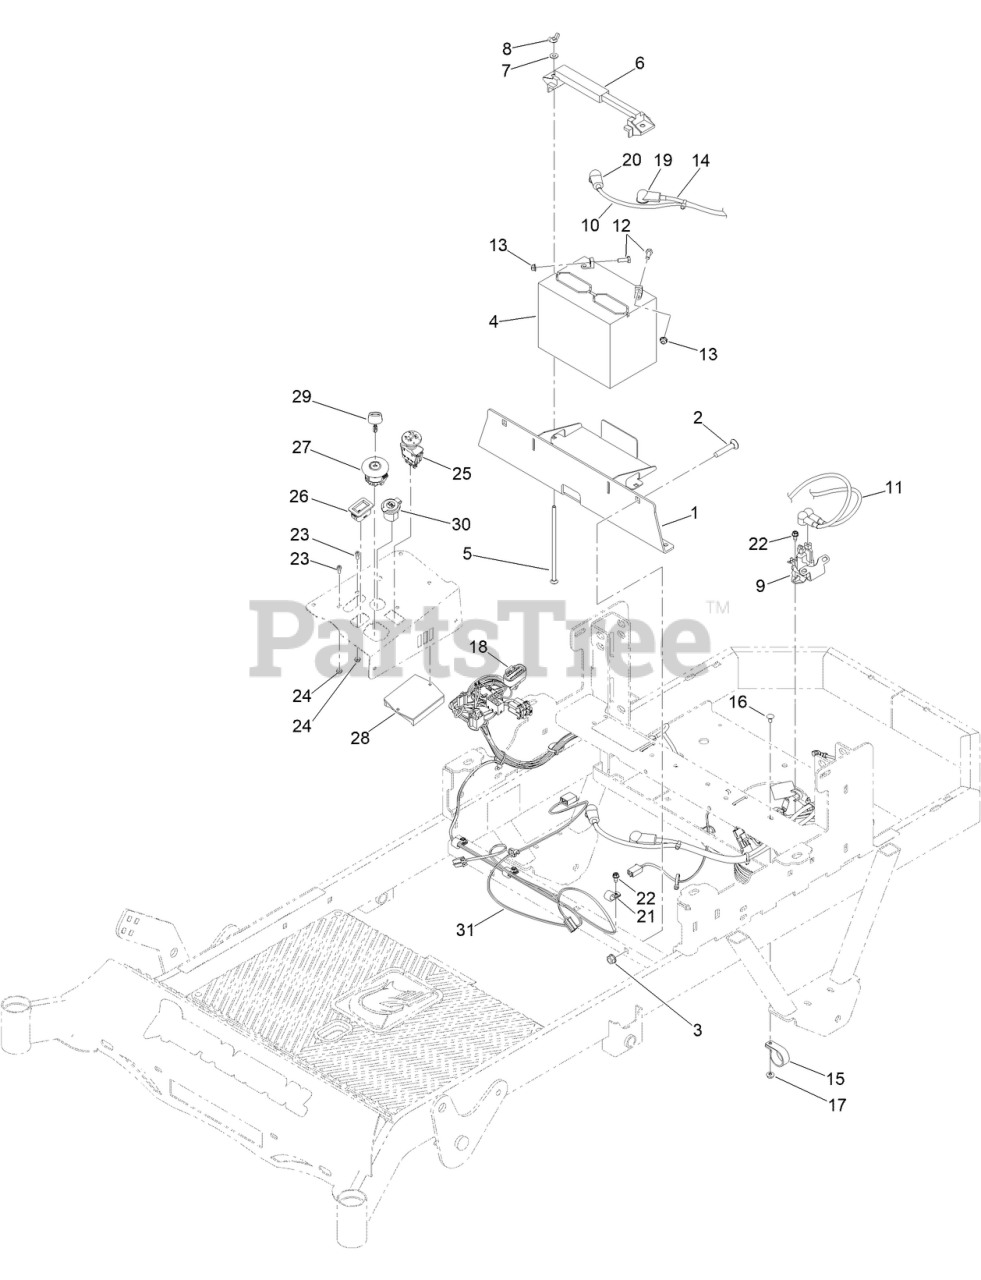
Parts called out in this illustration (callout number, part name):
1	MWR TTQ BATTERY BOX ASSY PAINT
2	SCREW-CARR
3	NUT-HHF, WHIZ
4	12 VOLT START BATTERY 300CCA
5	1/4-20 X 7 CARRIAGE BOLT ZINC
6	BATTERY HOLD DOWN
7	WASHER-FLAT
8	NUT-WING
9	HEAVY DUTY START SOLENOID
10	MWR NEGATIVE CABLE 28
11	MWR START WIRE 12
12	SCREW-HH
13	NUT-HF
14	MWR POSITIVE BATTERY CABLE 25IN
15	1-1/4IN CUSHIONED LOOP CLAMP BLACK
16	SCREW-CARR
17	1/4-20 HEX FLANGE NUT
18	MWR KEYSWITCH JUMPER HARNESS
19	3.15 LGTH STRAIGHT INSUL TERM COVER RED
20	STRAIGHT INSULATING TERMINAL COVER
21	CLAMP-R
22	SCREW-HWH
23	10-24 X 1/2 SOCKET C/S 18-8 SS
24	NUT-LOCK
25	PTO SWITCH
26	HOUR METER
27	IGNITION SWITCH
28	INTERLOCK MODULE
29	2023 MWR KEY
30	12 VOLT AUXILLIARY PLUG
31	RZ/RZ-PRO WIRING HARNESS
